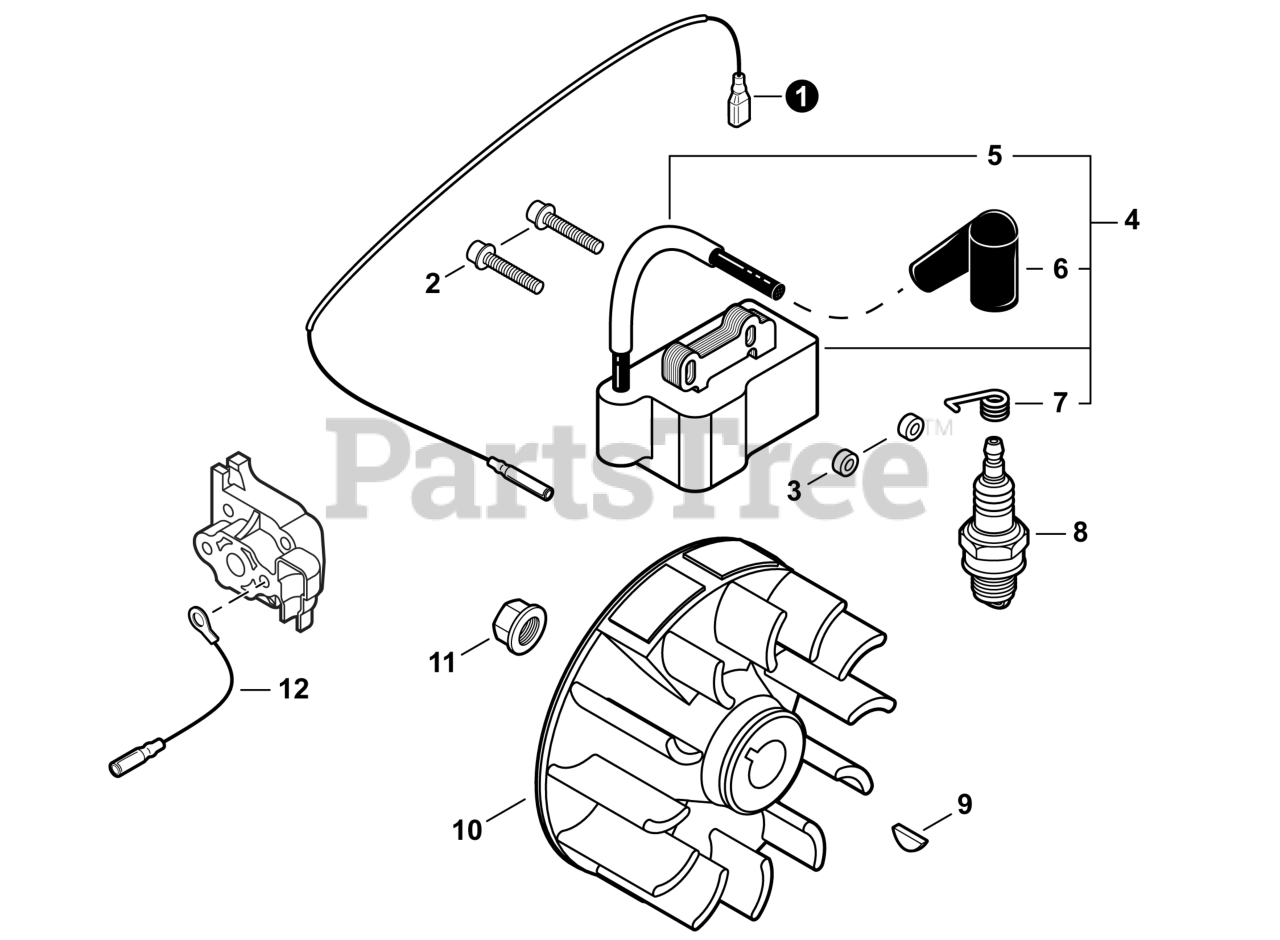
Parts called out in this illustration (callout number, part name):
1	LEAD - IGNITION L= 220 MM
2	BOLT M4×26
3	INSULATOR 4.2×11×6
4	COIL ASSY, IGNITION
5	TUBE, INSULATOR
6	CAP, SPARK PLUG
7	TERMINAL, SPARK PLUG
8	SPARK PLUG - CMR5H
9	KEY, WOODRUFF 3×10
10	FLYWHEEL
12	LEAD - GROUND L= 110 MM
